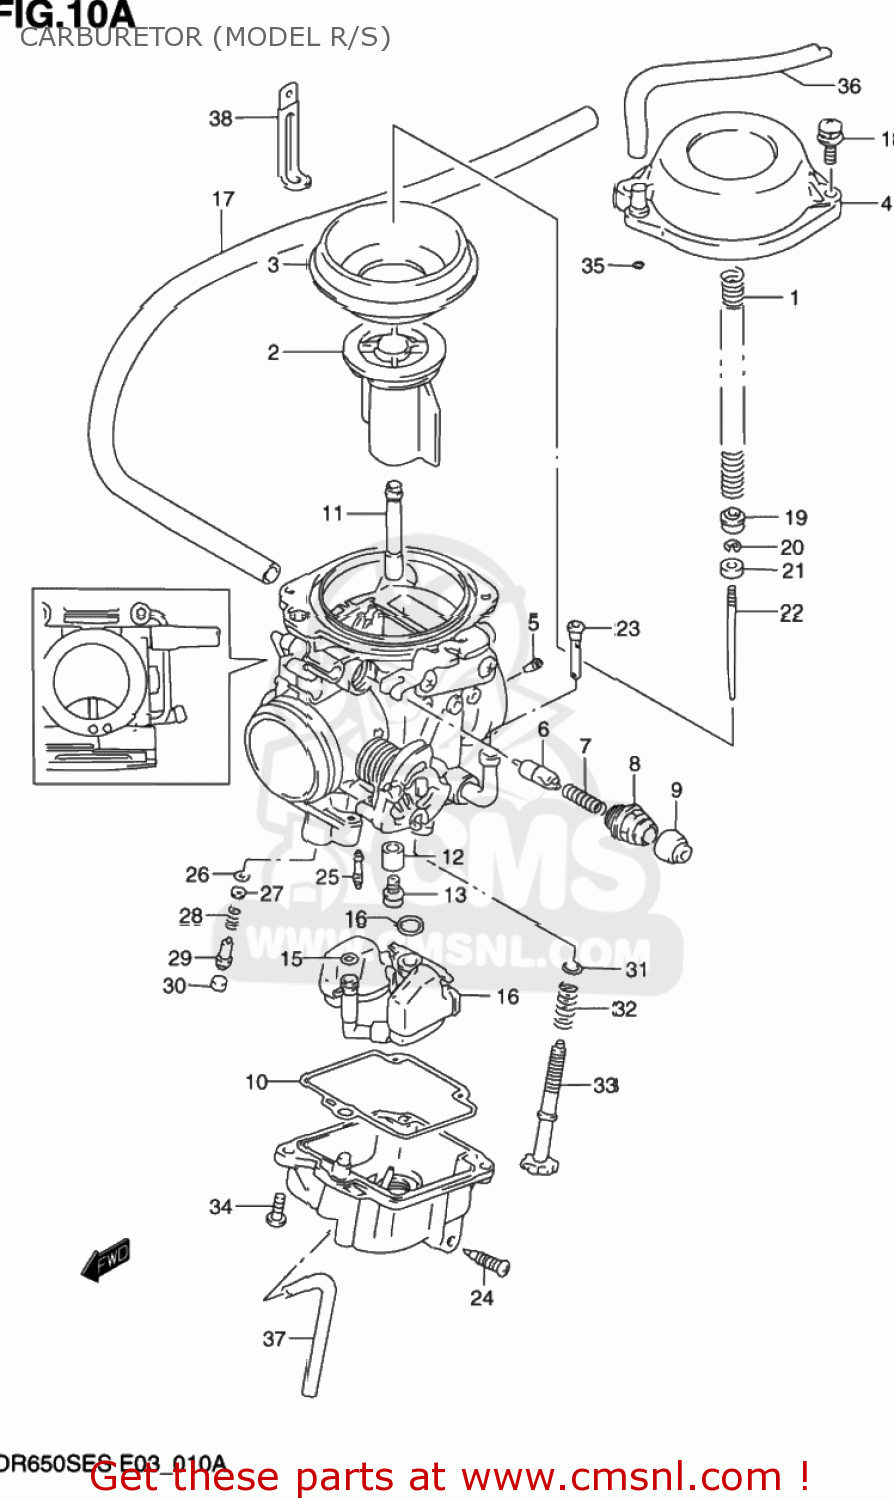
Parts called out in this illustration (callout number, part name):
1	SPRING
2	VALVE,PISTON
3	DIAPHRAGM
4	COVER,DIAPHRAGM
5	JET,AIR
6	PLUNGER
7	SPRING
8	HOLDER,GUIDE
9	CAP
10	GASKET,FLOAT CHAMBER (NAS)
11	JET,NEEDLE(Y-2)
12	RING
13	JET,MAIN(137.5)
14	FLOAT/NEEDLE VALVE ASSEMBLY
15	O RING
16	O-RING,NEEDLE VALVE
17	HOSE(6.5X11.5X600)
18	SCREW
19	RING
20	CLIP,NEEDLE
21	RING
22	NEEDLE,JET
23	FILTER
24	SCREW,DRAIN
25	JET,PILOT(52.5)
26	O RING,PILOT AIR SCREW
27	WASHER
28	SPRING
29	SCREW,PILOT
30	PLUG
31	WASHER
32	SPRING
33	ADJUSTER
34	SCREW(5X14)
35	O RING
36	HOSE (4.5X8.5X600)
37	HOSE
38	CLAMP
